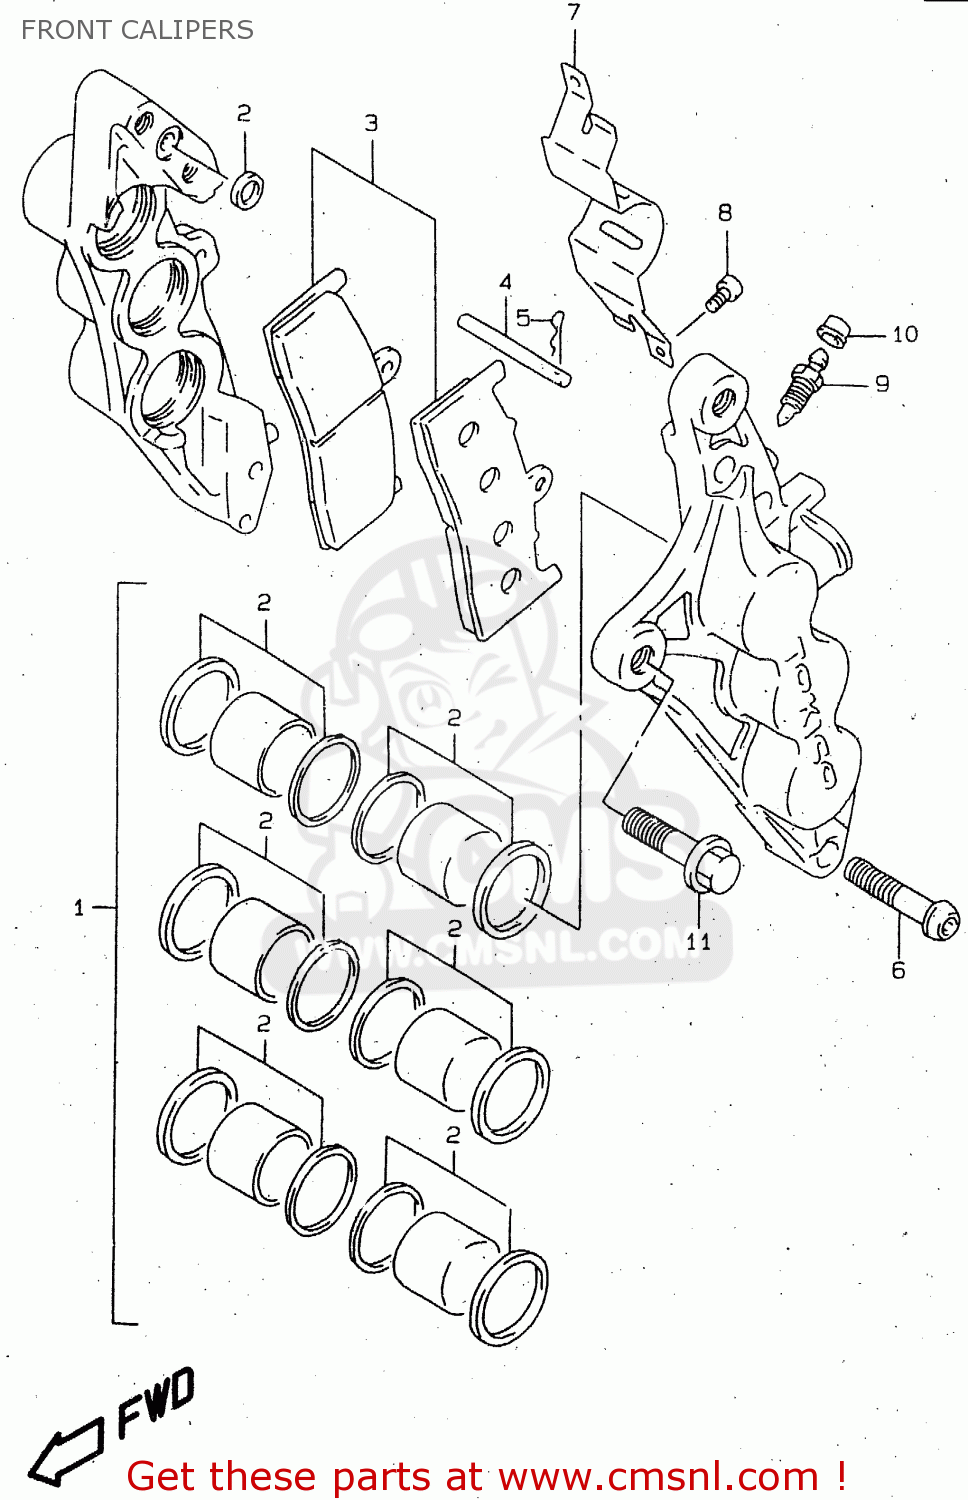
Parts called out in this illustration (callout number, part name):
1	PISTON SET
2	SEAL SET,PISTON
3	PAD SET (NAS)
4	PIN,PAD
5	CLIP,PAD PIN
6	BOLT,HOUSING
7	COVER,CALIPER
8	SCREW
9	BLEEDER
10	CAP,BLEEDER PLUG
11	BOLT(10X30)
